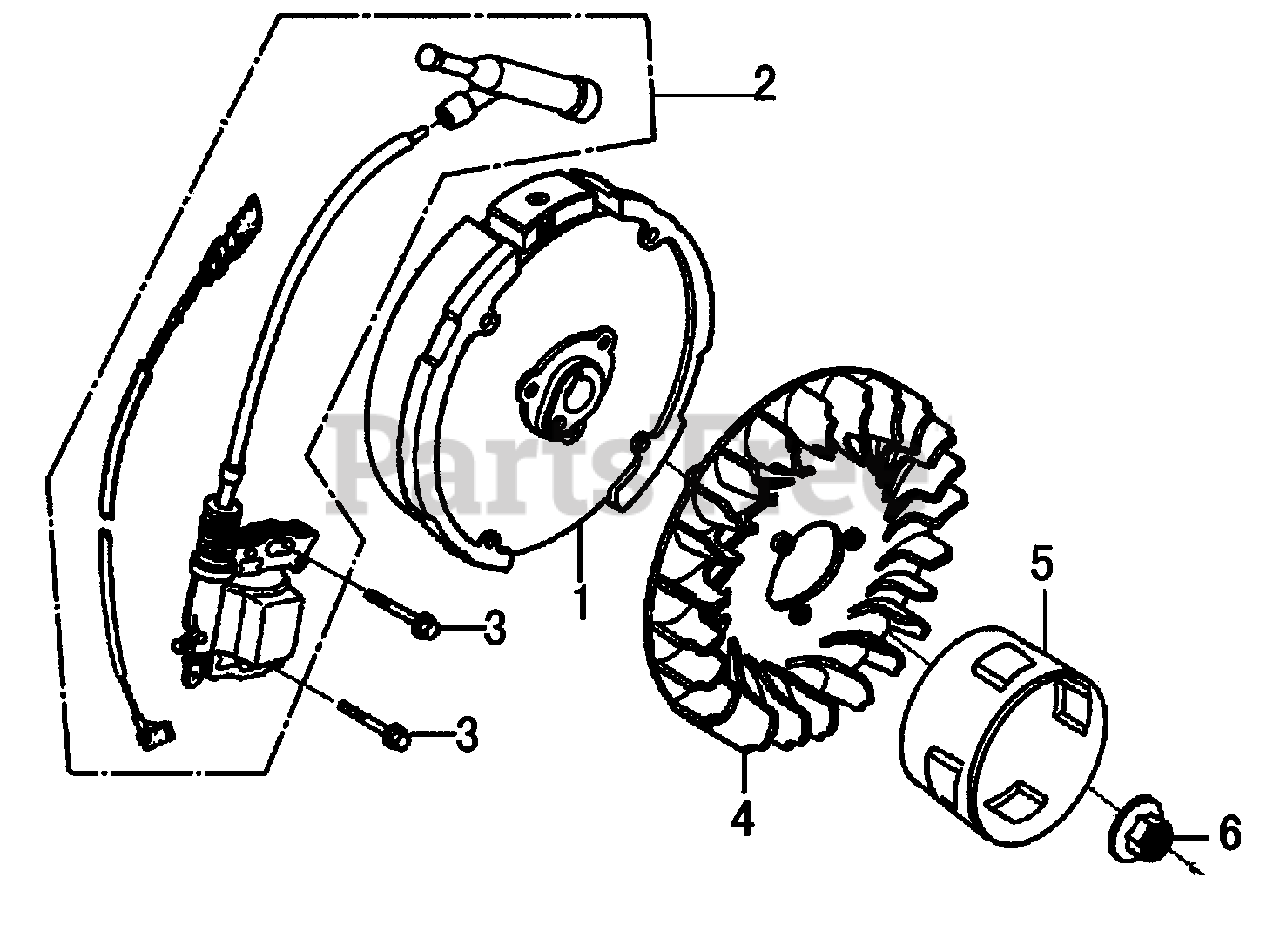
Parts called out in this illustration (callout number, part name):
1	FLYWHEEL COMP
2	COIL ASSY., IGNITION
3	BOLT, FLANGE
4	FAN, COOLING
5	PULLEY, STARTER
6	NUT, SPECIAL
